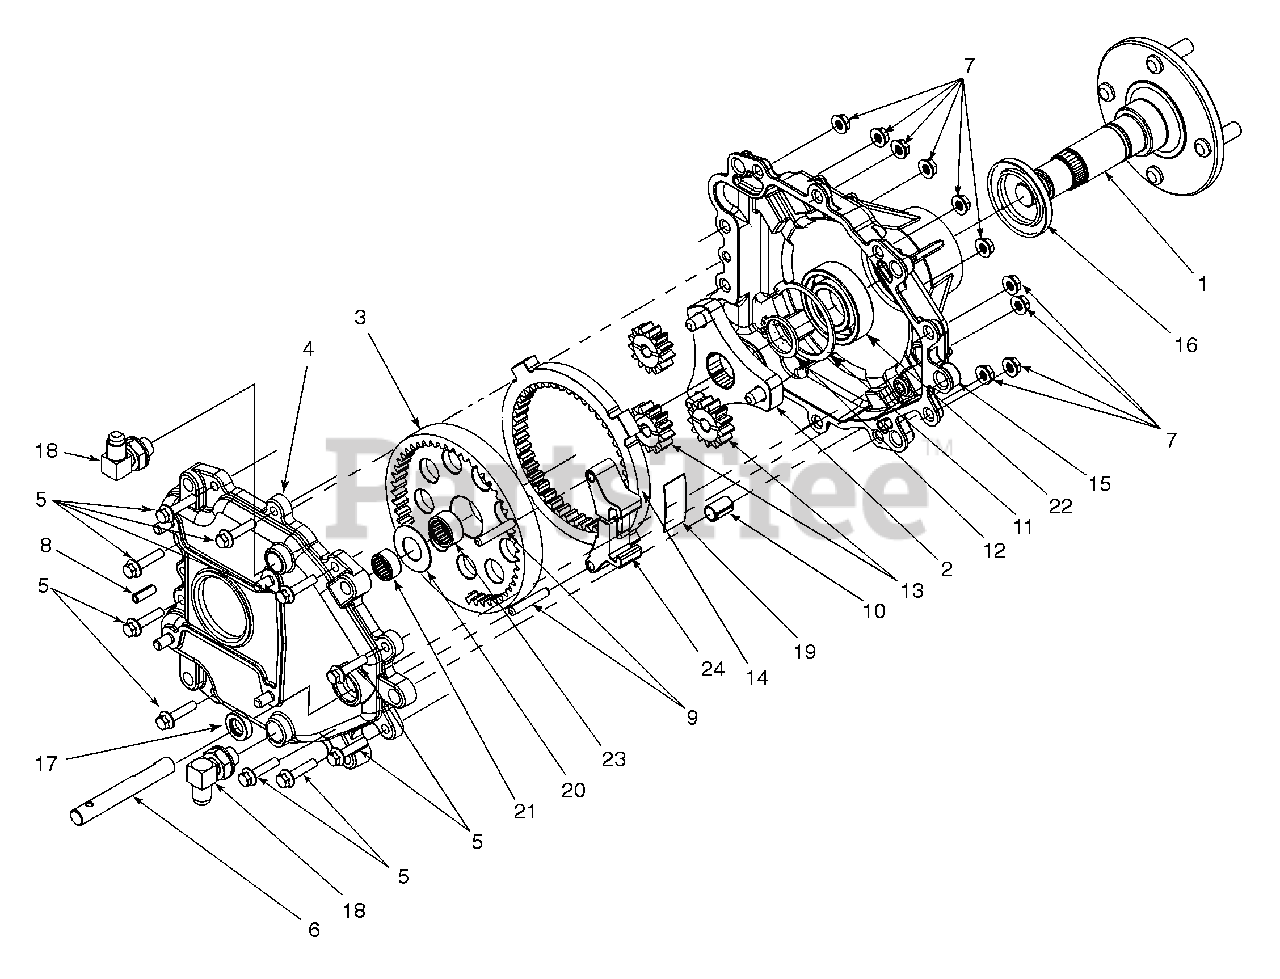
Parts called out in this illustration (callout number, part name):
1	Axle Assembly
2	Carrier Assembly, Output
3	Gear Assembly, 51T Internal & 20T
4	Housing Ass'y
5	Hex Washer Screw 1/4-20 x 1-1/8
6	Brake Shaft
7	Hex Flange Lock Nut 1/4-20
9	Dowel Pin
10	Bushing
11	Inverted Retaining Ring
12	Snap Ring
13	Spur Gear 13T
14	Ring Gear 46T
15	Axle Outer Housing
16	Oil Seal
18	Elbow Fitting
19	Brake Shoe Spring
20	Shim Washer .76 x 1.5 x .030
21	Needle Bearing
22	Ball Bearing
23	Needle Bearing
24	Shoe Brake
